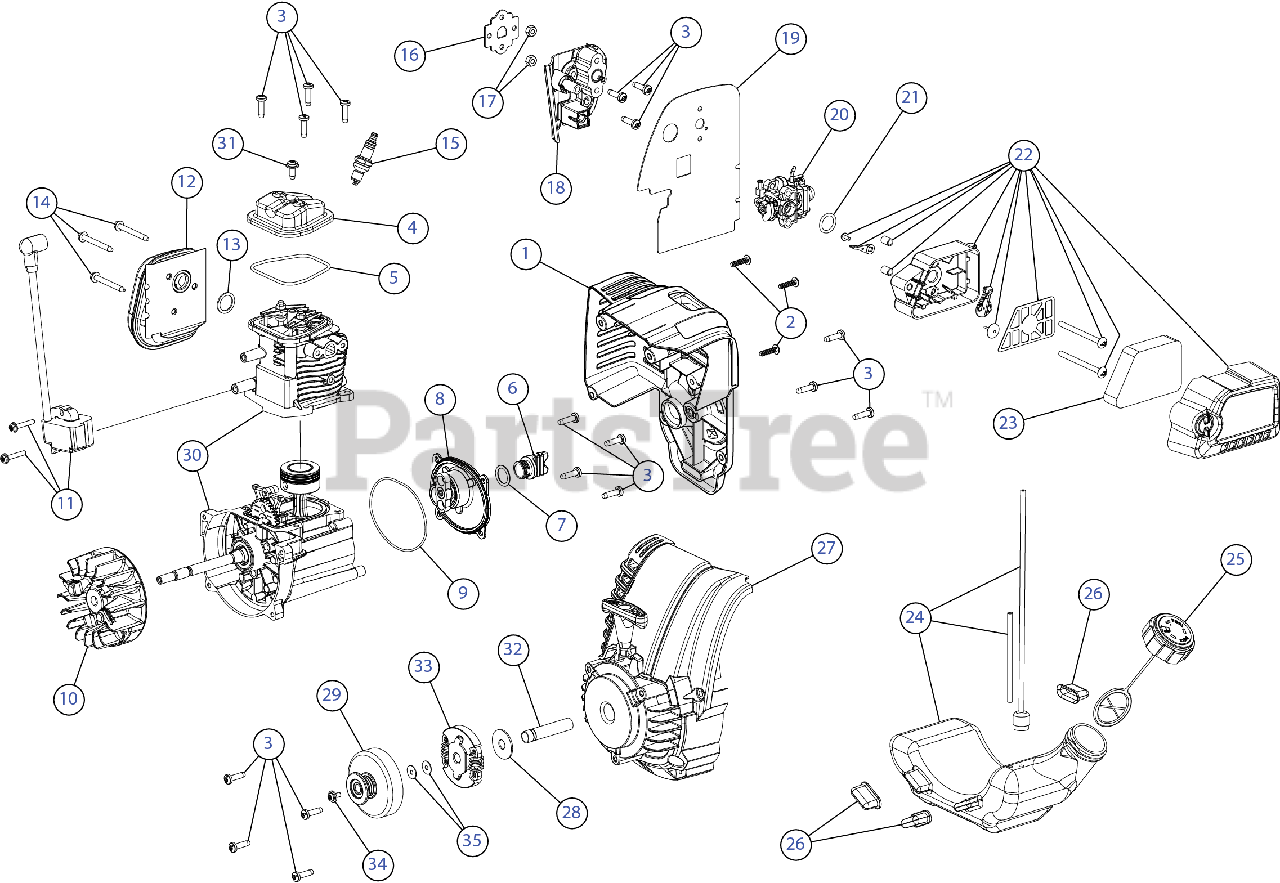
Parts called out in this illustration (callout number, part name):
1	REAR ENGINE CVR
2	SCREW 8-16 x 3/4
3	SCREW M5-0.8 x 19
4	ROCKER COVER
5	O-RING
6	OIL PLUG
7	RING, OIL PLUG (AC
8	CRANKCASE COVER
9	O-RING CRNKCSE CVR
10	FLYWHEEL ASSEMBLY AC3.1
11	MODULE MA89 DIG
12	MUFFLER ASSEMBLY
13	GASKET/MUFFLER
14	SCREW M5 x 44MM
15	SPARK PLUG 4 CYCL
16	GASKET/INSULATOR
17	NUT 10-32
18	INSULATOR
19	CARBURETOR GASKET
20	Carburetor (with Primer)
22	AIR CLEANER ASSEMBLY
23	AIR FILTER
24	FUEL TANK ASSEMBLY
25	FUEL CAP ASSEMBLY 43MM-6 W/O HOLE
26	FUEL TANK PADS
27	Starter Housing Assembly
28	WASH, CLUTCH O.D. 1.155 +/- .0
29	CLUTCH DRUM/PULLEY
30	SHORT BLOCK
31	SCR, VALVE COVER
32	SPACER :2.165"
33	CLUTCH WITH SPACER
34	SCREW 8-32X.375 PH S
35	WASH, NORAM CLUTCH
